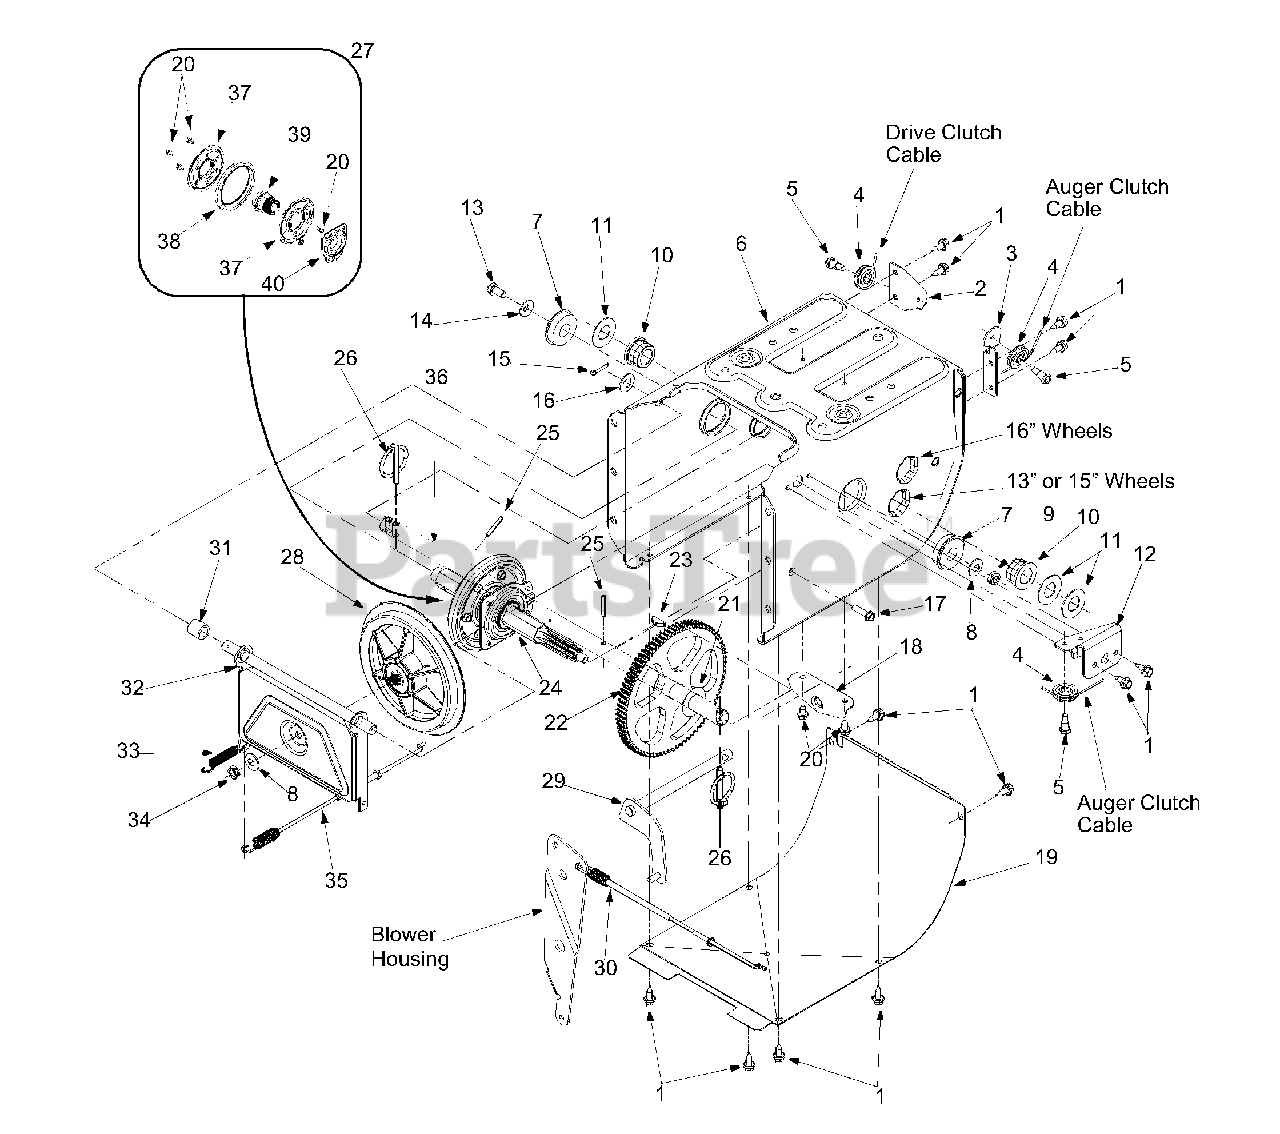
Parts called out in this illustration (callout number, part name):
1	Hex Screw
2	Drive Cable Guide Bracket
3	Auger Clutch Cable Bracket
4	Roller Cable
5	Hex Screw 1/4-28
8	Bell Washer
9	Lock Jam Nut
10	Hex Flange Bearing
11	Flat Washer
12	Front Support Guide Bracket
13	Lock Hex Screw
14	Bell Washer .340 ID x .872 OD
15	Cotter Pin
16	Flat Washer .536 ID x .930 OD
17	Hex Washer Screw 1/4-20
21	Flat Washer .760 ID x .50 OD
23	Key
24	7-Tooth Shaft
25	Roll Pin
26	Klik Pin
27	Friction Wheel Assembly
28	Friction Disc Wheel
29	Wheel Shift Rod Assembly
30	Drive Cable
31	Spacer
32	Friction Wheel Bracket Assembly
33	Extension Spring
34	Jam Nut 3/8-24
35	Drive Cable
36	Axle 13" Wheels (524)
36	Axle 16" Wheels (1028)
37	Friction Plate
38	Friction Wheel Rubber
39	Friction Wheel Hub
40	Friction Wheel Bearing
